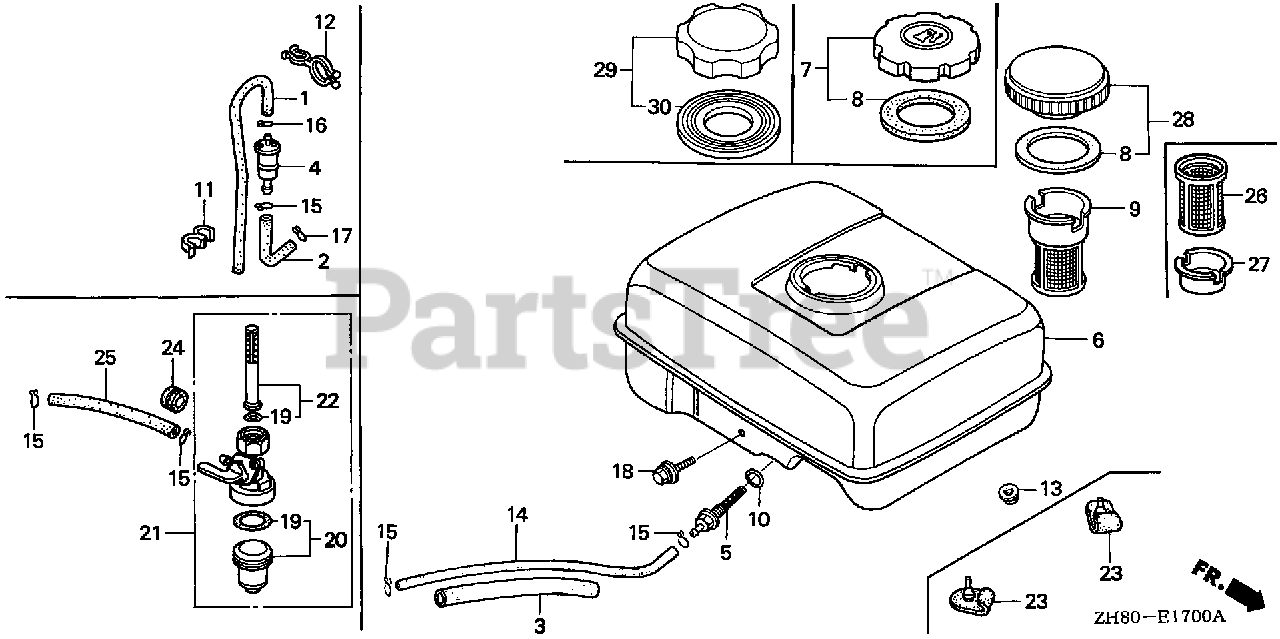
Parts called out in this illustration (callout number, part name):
3	RUBBER, SUPPORTER (107MM)
5	JOINT, FUEL TANK
6	TANK, FUEL *NH1* (BLACK)
7	CAP, FUEL FILLER (BLACK)
8	GASKET, FUEL FILLER CAP (39X58X3)
10	O-RING (14MM) (ARAI)
10	O-RING (14MM) (NOK)
13	NUT, FLANGE (6MM)
14	BULK HOSE, FUEL (4.5X3000) (4.5X140)
15	CLIP, TUBE (B8)
18	BOLT, FLANGE (6X25)
29	CAP, FUEL FILLER (CHROME PLATED)
29	CAP, FUEL FILLER (CHROME PLATED)(TOUYOUSYA)
30	GASKET, FUEL FILLER CAP (39X62X3) (TOUYOUSYA)
